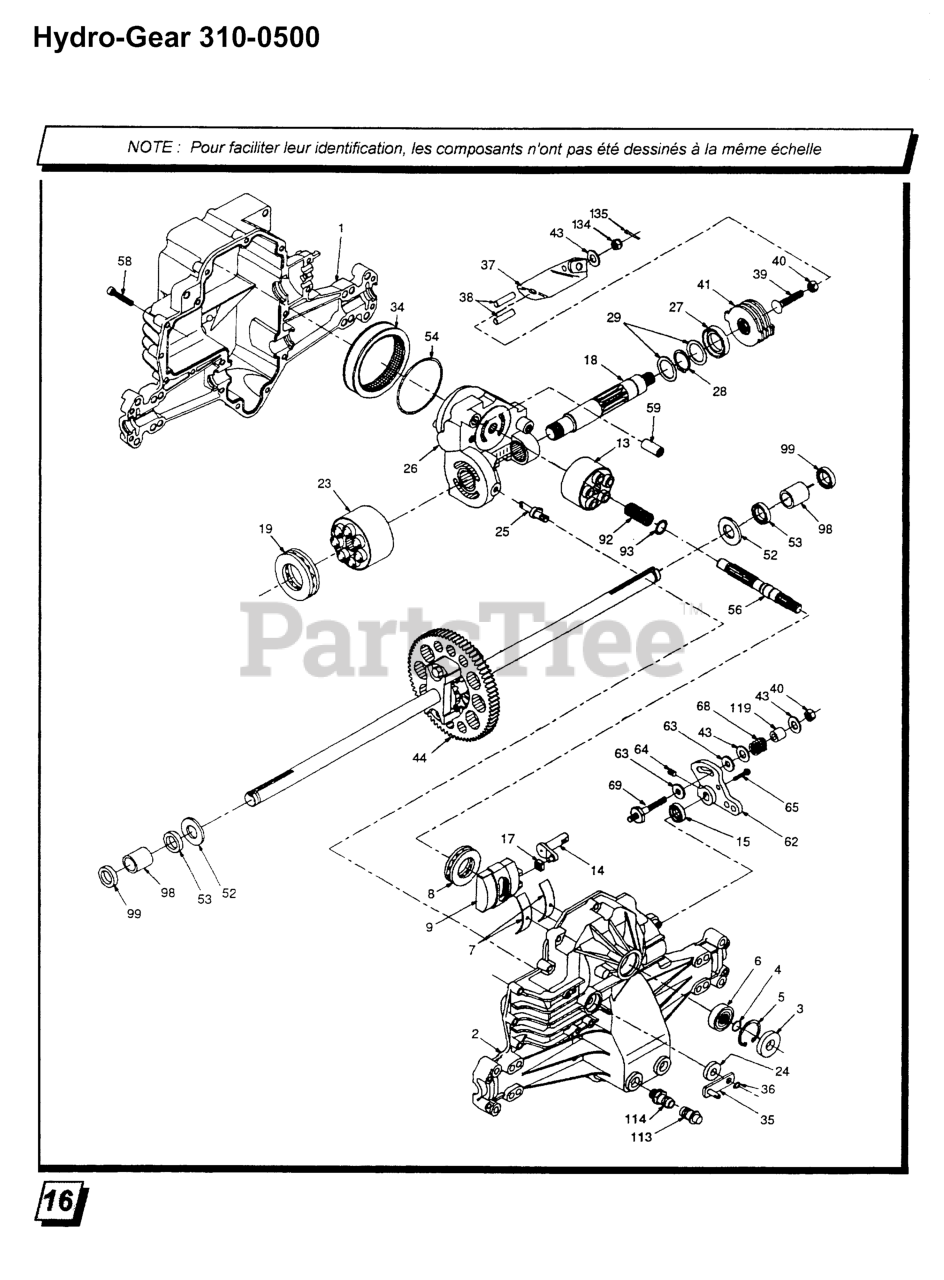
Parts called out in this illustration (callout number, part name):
1	HOUSING, LOWER
2	HOUSING.UPPER.70122.HYDRO-GEAR
3	SEAL.LIP.H-G.(9008000-0128)
4	RING RETAINING 2003016
5	RING.RETAINING.(2003052)
6	BALL BEARING
7	CRADLE BEARING
8	THRUST BEARING
9	SWASHPLATE (2003087)
13	BLOCK, CYL ASSY
14	TRUNNION ARM
17	SLOT GUIDE
18	REPL BY 532 15 07-72
19	THRUST BEARING
23	BLOCK, CYL ASSY
25	BYPASS ACTUATOR
26	CENTER SECTION ASSY KIT
28	RETAINING RING
34	ELEMENT, OIL FILTER
35	BYPASS ARM
36	RETAINING RING 44870
37	ACTUATING ARM
38	ACTUATING PIN 44891
40	NUT.LOCK.HX.(H-G PART 50108)
41	BRAKE ROTOR 70135 HYDRO-GEAR
43	WASHER .34X.88X.06.44130
44	DIFFERENTIAL ASSEMBLY
52	WASHER.HYDRO-GEAR 44875
53	SEAL.HYDRO.53901
56	SHAFT.INPUT.50005
58	BOLT #44876
62	CONTROL ARM 50254
63	DAMPENER PUCK
64	SCREW.SET.50018
68	SPRING HELICAL COMP 50277
69	STUD 5/16-24 50284
92	SPRING 2003014
98	BEARING SLV 50137
99	RP SEAL, WIPER
113	CAP, VENT ASSY
114	O-RING KIT 70110
119	SPACER.HYDRO GEAR 50278
134	NUT.CAS.HYD.44142
135	ID DOT HYDD
